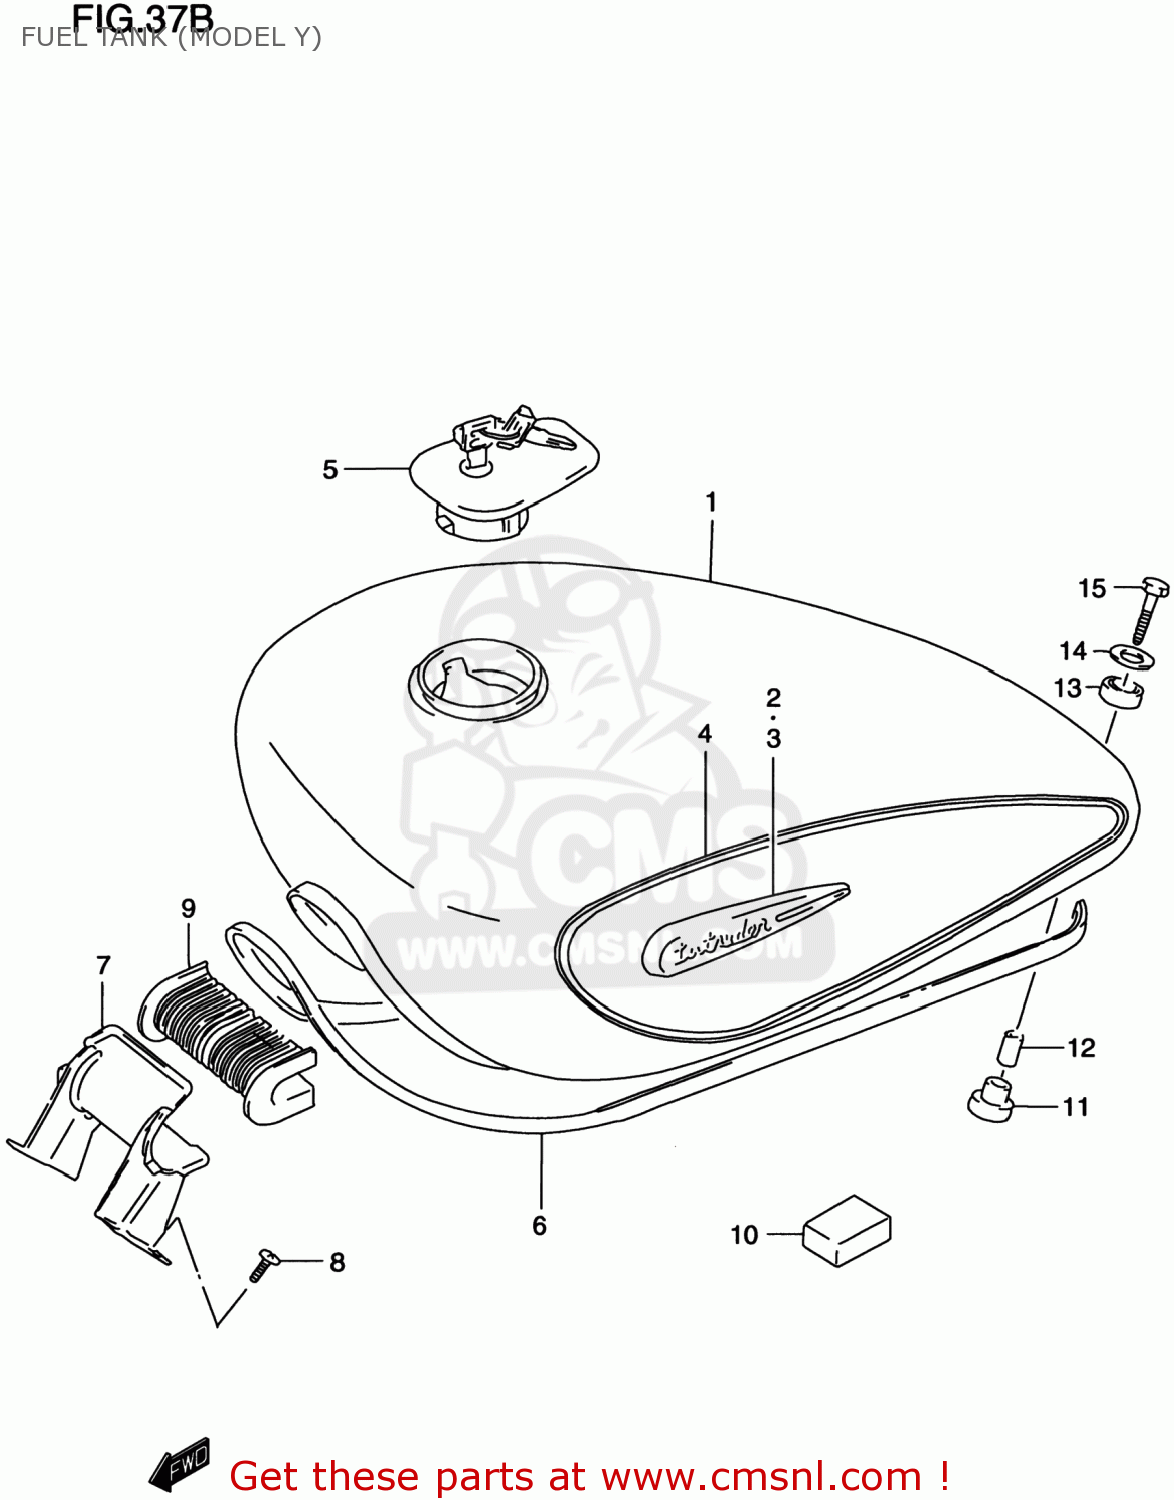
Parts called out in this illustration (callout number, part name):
1	TANK ASSEMBLY,FUEL
2	EMBLEM,FUEL TANK,R
3	EMBLEM,FUEL TANK,L
4	TAPE SET,FUEL TANK
5	CAP SET,FUEL TANK
6	MOLDING
7	BRACKET,FUEL TANK FR
8	SCREW
9	CUSHION,FUEL TANK FR
10	CUSHION
11	CUSHION
12	SPACER(6.5X9X21.5)
13	CUSHION
14	WASHER(6.5X24X1.6)
15	SCREW
